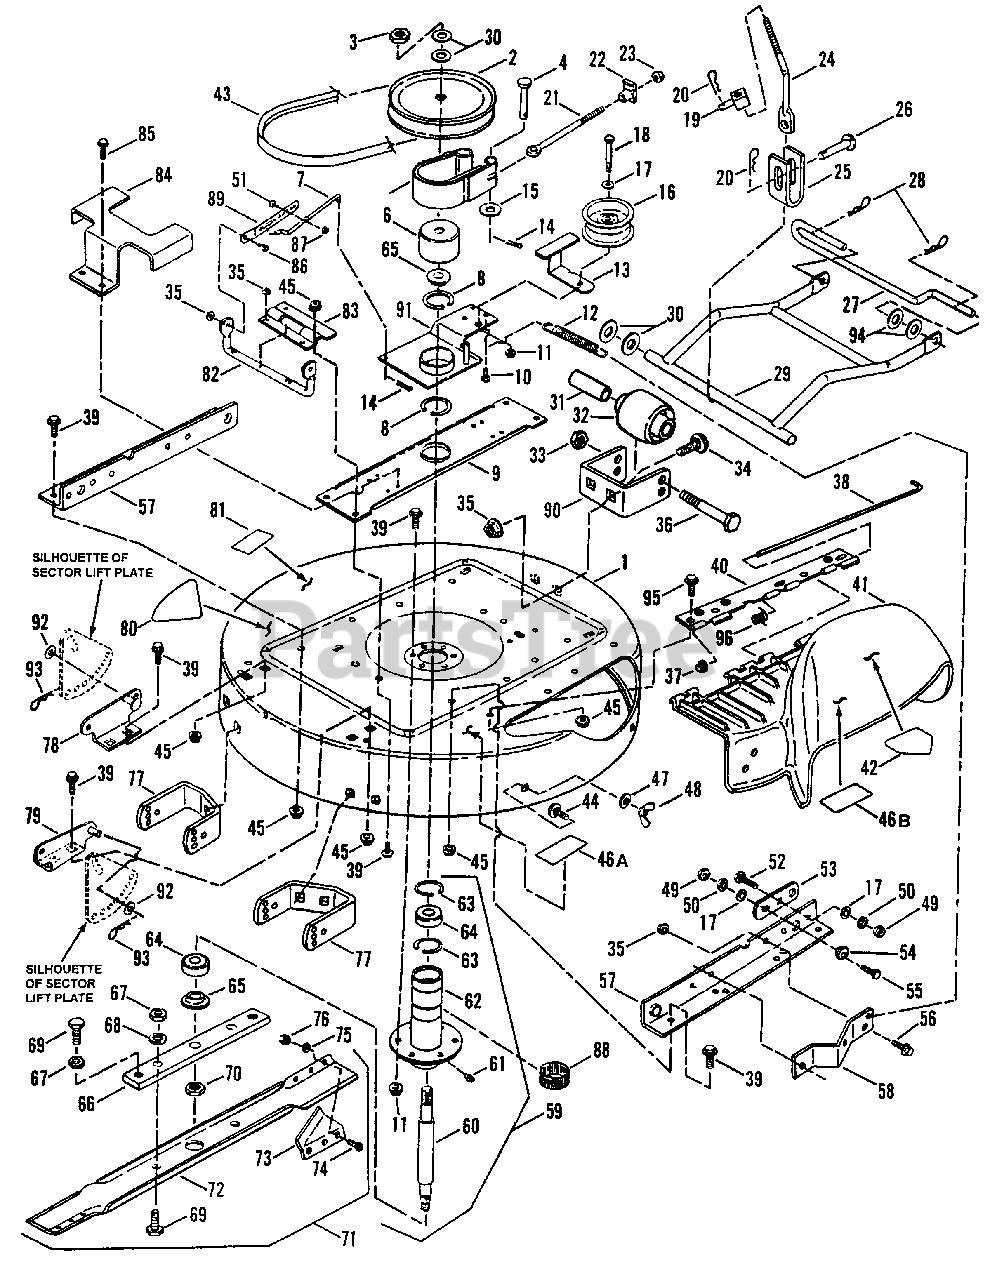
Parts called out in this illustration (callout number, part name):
1	ASSEMBLY, Deck, 33" Cutting
2	PULLEY, Spindle, 7" O.D.
3	NUT, 3/4-16 Hex Jam
4	PIN, 1/4 x 1 1/4" Clevis
5	ASSEMBLY, Brake Band
6	DRUM, Brake
7	ROD, Link, Clutch/Brake
8	RING, 2" External Retaining
9	BRACE, Spindle
10	SCREW, 5/16-18 x 3/4" Self-Tapping
11	NUT, 3/8-16 Hex Center Lock
12	SPRING, Clutch & Brake
13	GUIDE, Belt
14	COTTER-PIN, 3/32 x 3/4"
15	WASHER, Flat
16	PULLEY, Idler, 4" O.D.
17	WASHER, 3/8 SAE Flat
18	SCREW, 3/8-16 x 1 3/4" Hx. Hd. Cap
19	SWIVEL, Brake
20	PIN, 1/4 x 1 1/8" Hair
21	BOLT, 1/4-20 Eye
22	NUT, 1/4-20 Tee
23	NUT, 1/4-20 Hex
24	ROD, Front Lift
25	BRACKET, Front Lift Hanger
26	PIN, 3/8 x 1 1/2" Clevis
27	PIN, Front Deck Hanger
28	PIN, Hair, .148 x 2.62"
29	LIFT, Front Arm
30	WASHER, Flat
31	SPACER
32	WHEEL, Gage
33	NUT, 3/8-24 Hex Center Lock
34	BOLT, 5/16-18 x 1/2" Short Neck Carriage
35	NUT, 5/16-18 Hex Flange Lock
36	SCREW, 3/8-24 x 3 3/4" Hex Head Cap, Grade 5
37	PAL-NUT, 1/4 Hex
38	PIN, Hinge
39	BOLT, 3/8-16 x 3/4" Hx. Flge. Lk.
40	HINGE, Deflector
41	ASSEMBLY, Deflector
41	DEFLECTOR, Discharge
42	DECAL, Danger (Cut Finger)
43	BELT, Drive, 33" Cutting Deck 56.95" EL
44	BOLT, 5/16-18 x 3/4" Short Neck Carriage, Grade 5
45	NUT, 3/8-16 Hex Flange Lock
46A	DECAL - CAUTION, Deflector
46B	DECAL - CAUTION, Deflector
47	WASHER, 5/16 Flat
48	NUT, 5/16-18 Wing
49	NUT, 3/8-16 Hex
50	WASHER, 3/8 Split Lock
51	BOLT, 1/4-20 x 1/2" Hex Flange Lock
52	BOLT, 3/8-16 x 3/4" Carriage
53	LINK, Adjustment
54	ECCENTRIC, Leveling
55	SCREW, 3/8-16 X 1" Hex Head Cap
56	BOLT, 5/16-18 x 1/2" Hex Flange Lock
57	RAIL, Side
58	ANCHOR, Brake
59	ASSEMBLY, Spindle
60	SPINDLE
61	FITTING, Lube (Press fit for .187 hole-no ball)
62	HOUSING, Spindle
63	RING, Retaining
64	BEARING, Spindle
65	WASHER, Spindle
66	HOLDER, Blade
67	NUT, 1/2-20 Hex Jam
68	WASHER, 1/2 Int. Tooth Lock
69	SCREW, 1/2-20 Hex Head Cap
70	NUT, 5/8-18 Hex Lock
71	ASSEMBLY, Blade & Air Lift
72	BLADE, 33" Cutting Deck
73	AIR-LIFT
74	SCREW, 5/16-24 x 11/16" Machine
75	WASHER, 5/16 Int. Tooth Lock
76	NUT, 5/16-24 Hex
77	BRACKET, Gage Wheel (Rear)
78	BRACKET, Rear Deck Lift, Left Side
79	BRACKET, Rear Deck Lift, Right Side
80	DECAL, 33" Hi-Vac
81	DECAL - CAUTION
82	ARM, Pivot
83	BRACKET, Pivot Arm
84	GUIDE, Belt
85	SCREW, 5/16-18 x 5/8" Self-Tap.
86	SCREW, 5/16-18 x 3/4" Shoulder
87	NUT, 1/4-20 Hex Flange Lock
88	RING, Tolerance
89	BRACKET, Link, Clutch/Brake
90	BRACKET, Gage Wheel (Front)
91	ARM, Idler
92	WASHER, 3/8" Flat
93	PIN, Hair, 093 x 1.50"
94	WASHER, Flat
95	BOLT, 3/8-16 x 3/4" Hex Flange Lock, Grade 5
96	SPRING, Hinge
